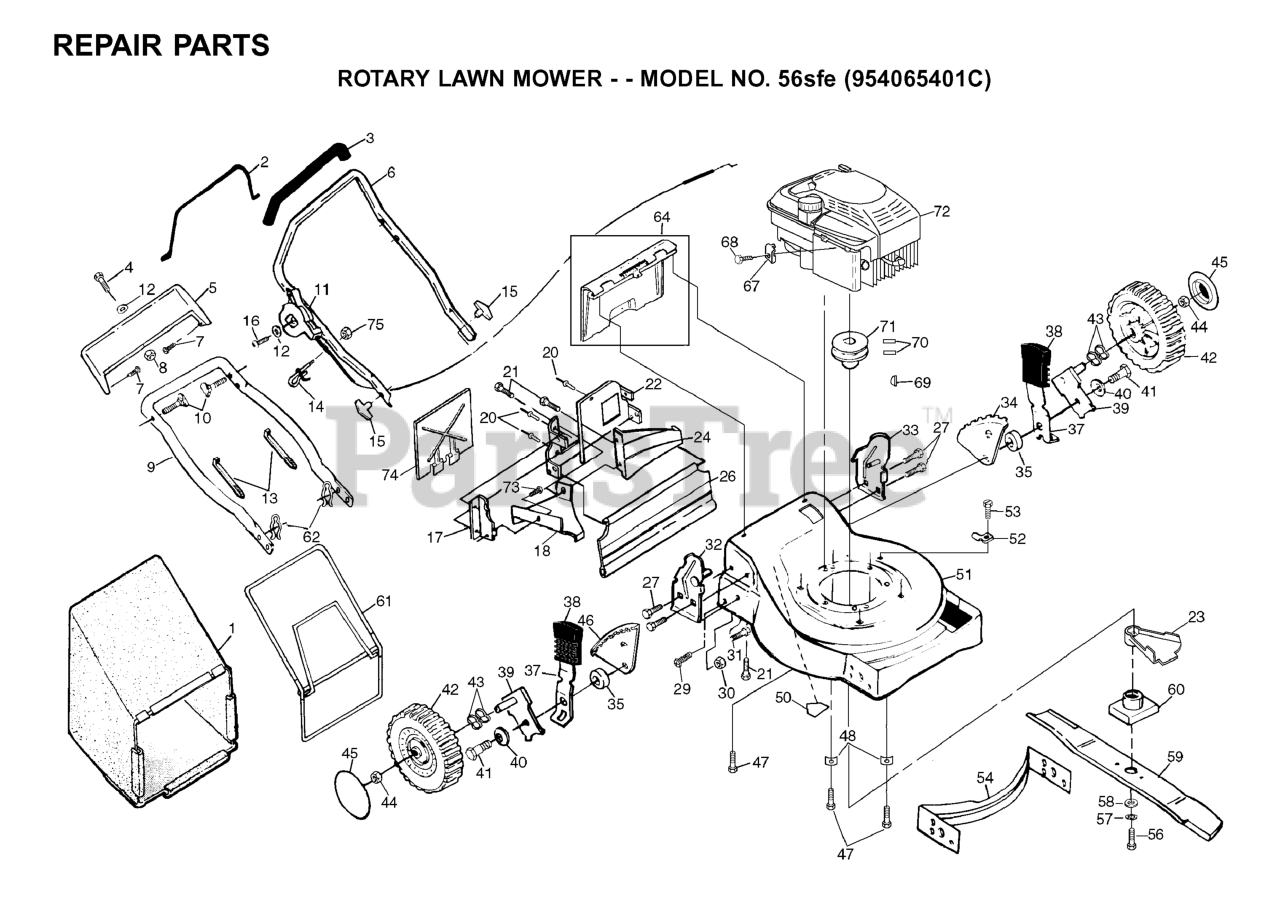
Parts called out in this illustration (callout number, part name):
1	GRASS BAG
2	CONTROL BAR
3	HANDLE GRIP
4	SCREW
5	TRIM PLATE
6	UPPER HANDLE
8	NUT
9	HANDLE, LOWER PM
10	HANDLE BOLT
11	THROTTLE CONTROL
13	TIE GUIDE
14	ROPE GUIDE
15	HANDLE KNOB
17	SIDE BAFFLE
18	DISCHARGE BAFFLE
20	RIVET BLIND
22	BACK PLATE
23	DEBRIS SHIELD
24	REAR BAFFLE
26	REAR SKIRT
27	SCREW
29	HINGE SCREW
30	LOCKNUT PM
32	HANDLE BRACKET RH
33	HANDLE BRACKET LH
34	WHEEL ADJ BRKT RR-LF
35	SPACER PM
37	SELECTOR SPRING
38	SELECTOR KNOB
39	AXLE ARM ASSY FT
40	WASHER.BELLEVILLE (3 2 LB)
41	BOLT
42	WHL & TIRE ASSEMBLY
43	WAVE WASHER
44	HEX FLANGE LOCKNT
46	WHEEL ADJ BRKT RF-LR
47	BOLT
48	WASHER.ENGINE.BZP
50	DECAL HYT
51	HOUSING (INCL KEY #50)
52	GUIDE CLIP PM
53	TAPPING SCREW
54	FRONT BAFFLE
56	SCREW, HEX HD 3/8-24 X 1-3/8
57	LOCKWASHER
58	WASHER,HARDEN
60	BLADE ADAPTOR
61	CATCHER.FRAME.WALK
62	HAIRPIN COTTER
64	REAR DOOR ASSEMBLY
68	SCREW.HEX.HEAD.WASHER.10-16
69	HI PRO KEY PM WSL
71	ENGINE.PULLEY.FWG
74	MULCHER PLATE
75	NUT
